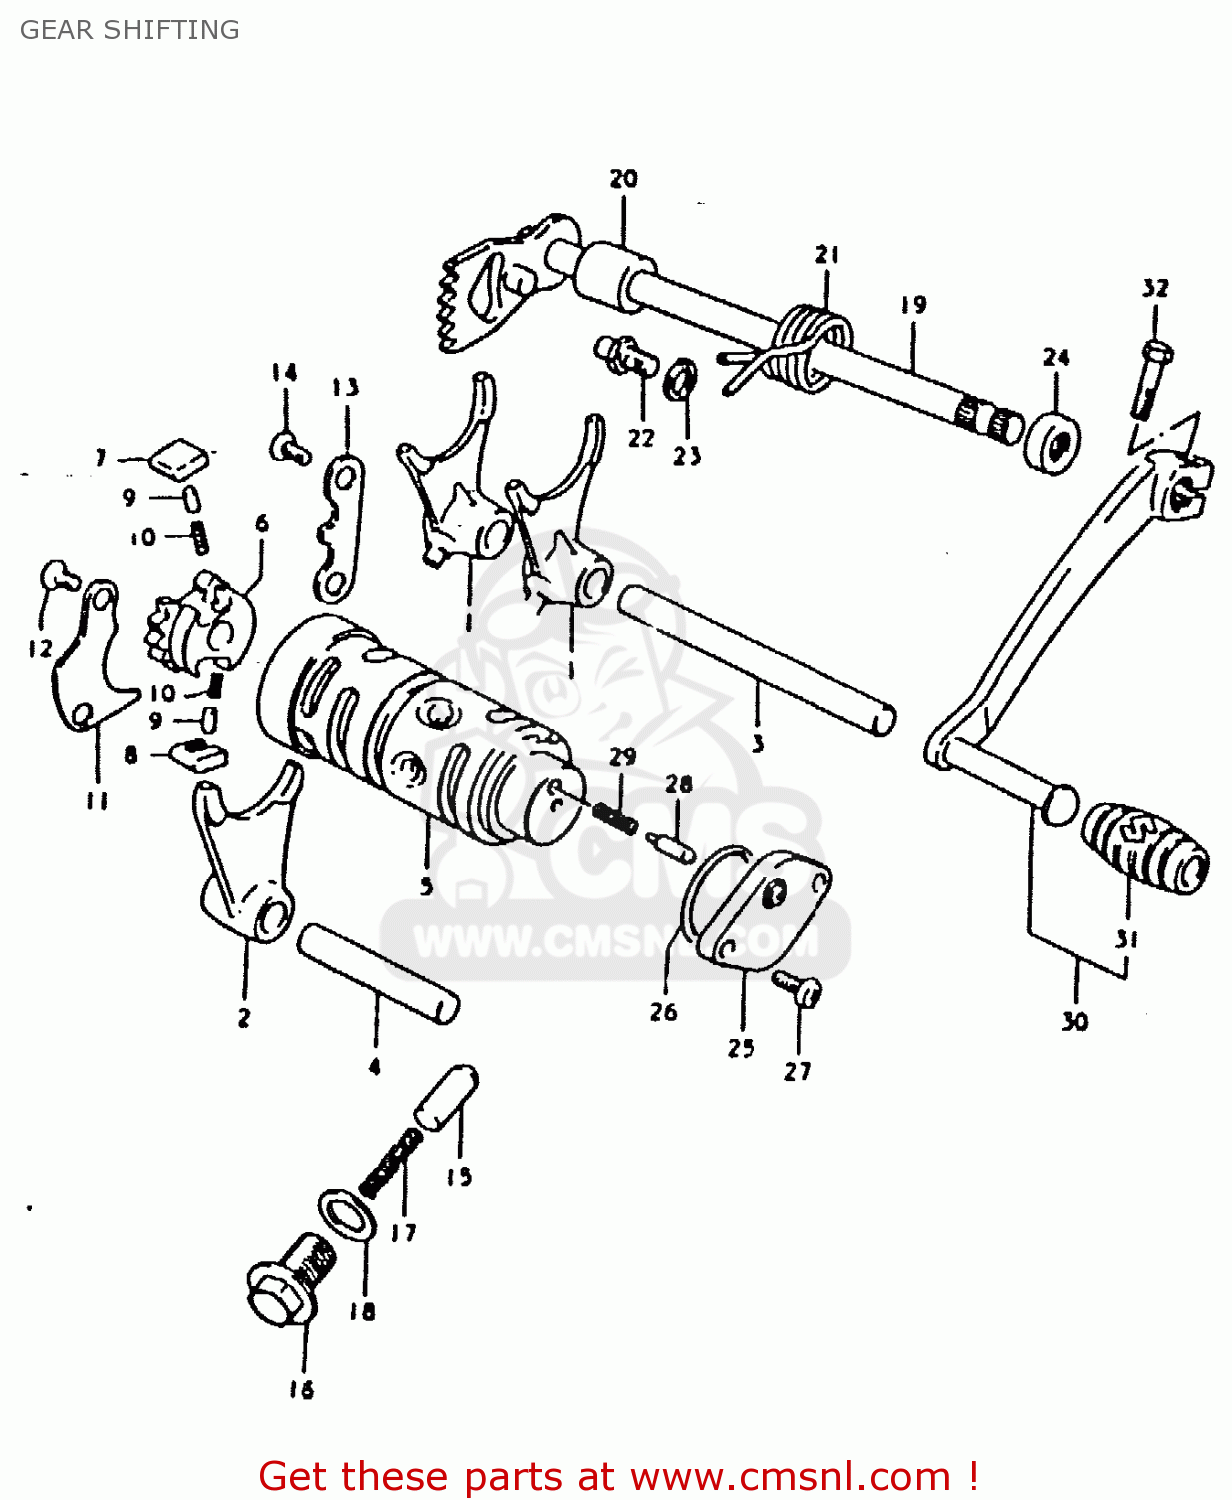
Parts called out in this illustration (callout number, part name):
1	FORK,GEAR SHIFT NO.1
2	FORK,GEAR SHIFT NO.2
3	SHAFT,GEAR SHIFT FORK
4	SHAFT,GEAR SHIFT FORK
5	CAM,GEAR SHIFT
6	RETAINER,GEAR SHIFT CAM
7	PAWL,GEAR SHIFT NO.1
8	PAWL,GEAR SHIFT NO.2
9	PIN(5X8)
10	SPRING
11	LIFTER,GEAR SHIFT PAWL
12	SCREW
13	GUIDE,GEAR SHIFTING CABLE
14	SCREW
15	STOPPER,GEAR SHIFTING
16	BOLT,GEAR SHAFT CAM STOPPER
17	SPRING
18	GASKET(14X19.2X2) (NAS)
19	SHAFT,GEAR SHIFT
20	SPACER(12X20X15.3)
21	SPRING
22	STOPPER,GEAR SHIFT CAM
23	WASHER
24	OIL SEAL
25	BODY,GEAR SHIFT SWITCH
26	O-RING (D:2.4 ID:26.2)
27	SCREW
28	PIN(5X15.5)
29	SPRING
30	LEVER ASSY,GEAR SHIFT
31	RUBBER,GEAR SHIFT PEDAL
32	BOLT
